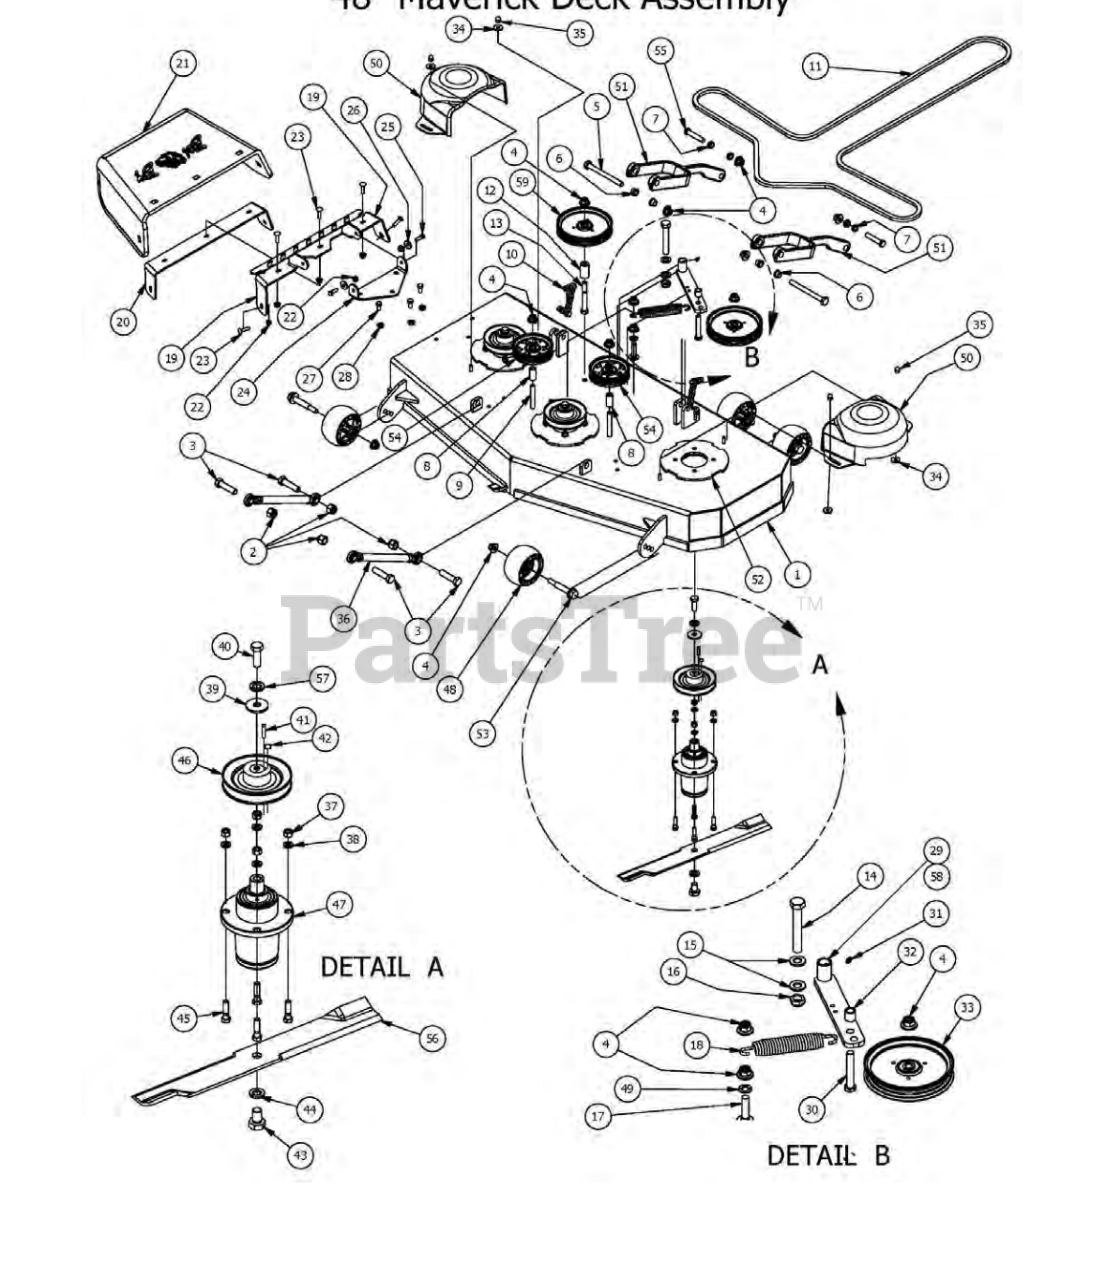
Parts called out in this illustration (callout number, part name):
1	ZT/Maverick 48" Deck
2	5/8 Std NC Nylock Nut
3	5/8" x 2 1/2" Grade 5 Hex Bolt (Coarse)
4	1/2-13 Nylon Flange Nut
5	1/2" x 5 1/2" Bolt
6	Flange Bushing For Upper Deck Arm
7	Flange Bushing For Lower Deck Arm
8	.502 ID X.750 OD X 1.500 Long Spacer
9	1/2 x 3 1/2 Flange Bolt Grade 8
10	6 Link Chain assembly
11	48 Deck Belt
12	1 3/4" Pulley Spacer
13	1/2" x 4" Bolt (Grade 8)
14	5/8" x 4" Hex Bolt
15	.630 ID Plastic Washer
16	5/8-11 Nylon Insert Jam Half Nut
17	1/2 x 2" Camage Bolt
18	2009 Deck/Pump Idler Spring
19	Discharge Upper Chute Bracket
20	Discharge Lower Chute Bracket
21	Rubber Discharge Chute
22	5/16" Nylon Flange Nut
23	5/16" x 1 1/4" Carriage Bolt
24	Discharge Chute Hanger (Deck Mounted)
25	5/16" x 1" Bolt
26	360 ID Plastic Washer
27	3/8" x 3/4" Hex Bolt.
28	3/8" Flange Nut
29	Deck Idler
30	1/2-13 x GR 5 Hex Bolt Zinc
31	1/4" Press in Grease Fitting
32	Spacer 3/4 OD x 1/2 ID x 3/4 Length
33	5-3/4 Idler Pulley-Don Dye
34	360 ID Plastic Washer-Black
35	Acorn nut-pulley Cover
36	Turnbuckle (Top Link)
37	3/8" Hex Nut
38	3/8" Lock Washer
39	1/2 Belleville Washer
40	1/2"-20 x 1 1/2 - Grade 5 Fine Thread Bolt
41	1/4" x 1" Key
42	5/16 Set Screw
43	5/8" x 1 1/2" Grade 8 Hex Bolt (Fine)
44	5/8" Lock Washer
45	3/8" x 1 1/2" Hex Bolt
46	5" Spindle Deck Pulley
47	Spindle Assembly
48	Anti-Scalp Rollers
49	.517 Square Hole Round Washer
50	Pulley Cover
51	Deck Arm Assembly
52	Deck Spindle Support Plate
53	Deck Wheel Bolt
54	4-3/4 Idler Pulley
55	1/2" x 3" Hex Bolt
56	Fusion Blade
57	1/2" Lock Washer Zinc
58	Idler Arm Assembly (Parts 4,29,30,31,32,33)
59	5-3/4 Idler Pully
